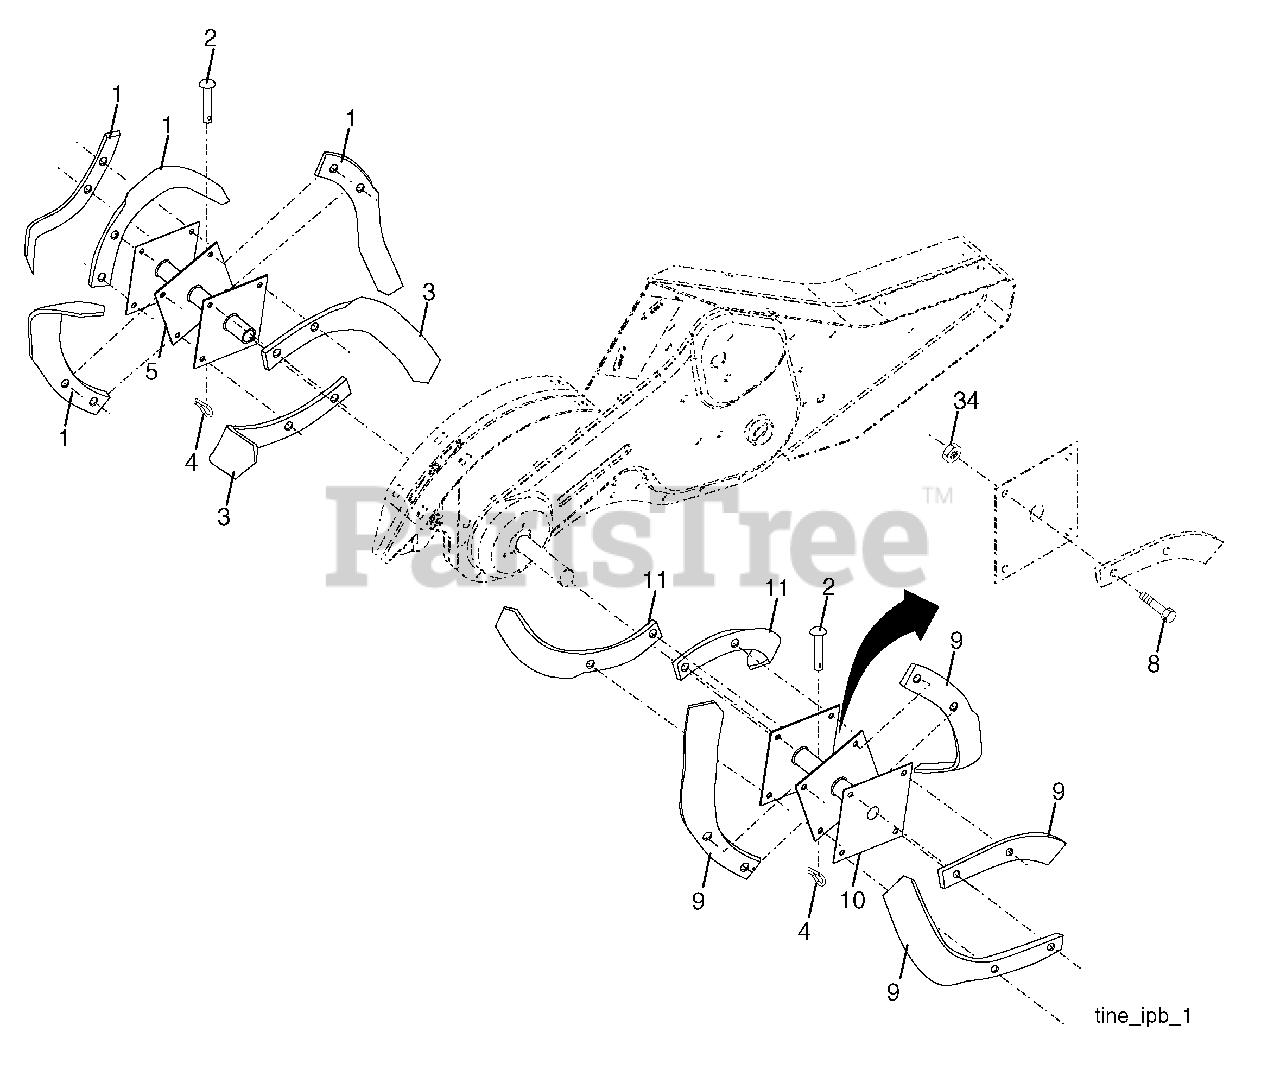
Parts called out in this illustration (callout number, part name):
1	Tine, Outer, L.H.
2	Clevis Pin
3	Tine, Inner, L.H.
4	Retainer, Spring Zinc
5	Assembly, Hub and Plate, L.H.
8	Bolt, Hex 3/8-24 x 1
9	Tine, Outer, R.H.
10	Assembly, Hub and Plate, R.H.
11	Tine, Inner, R.H.
34	Nut Crownlock 3/8-24
